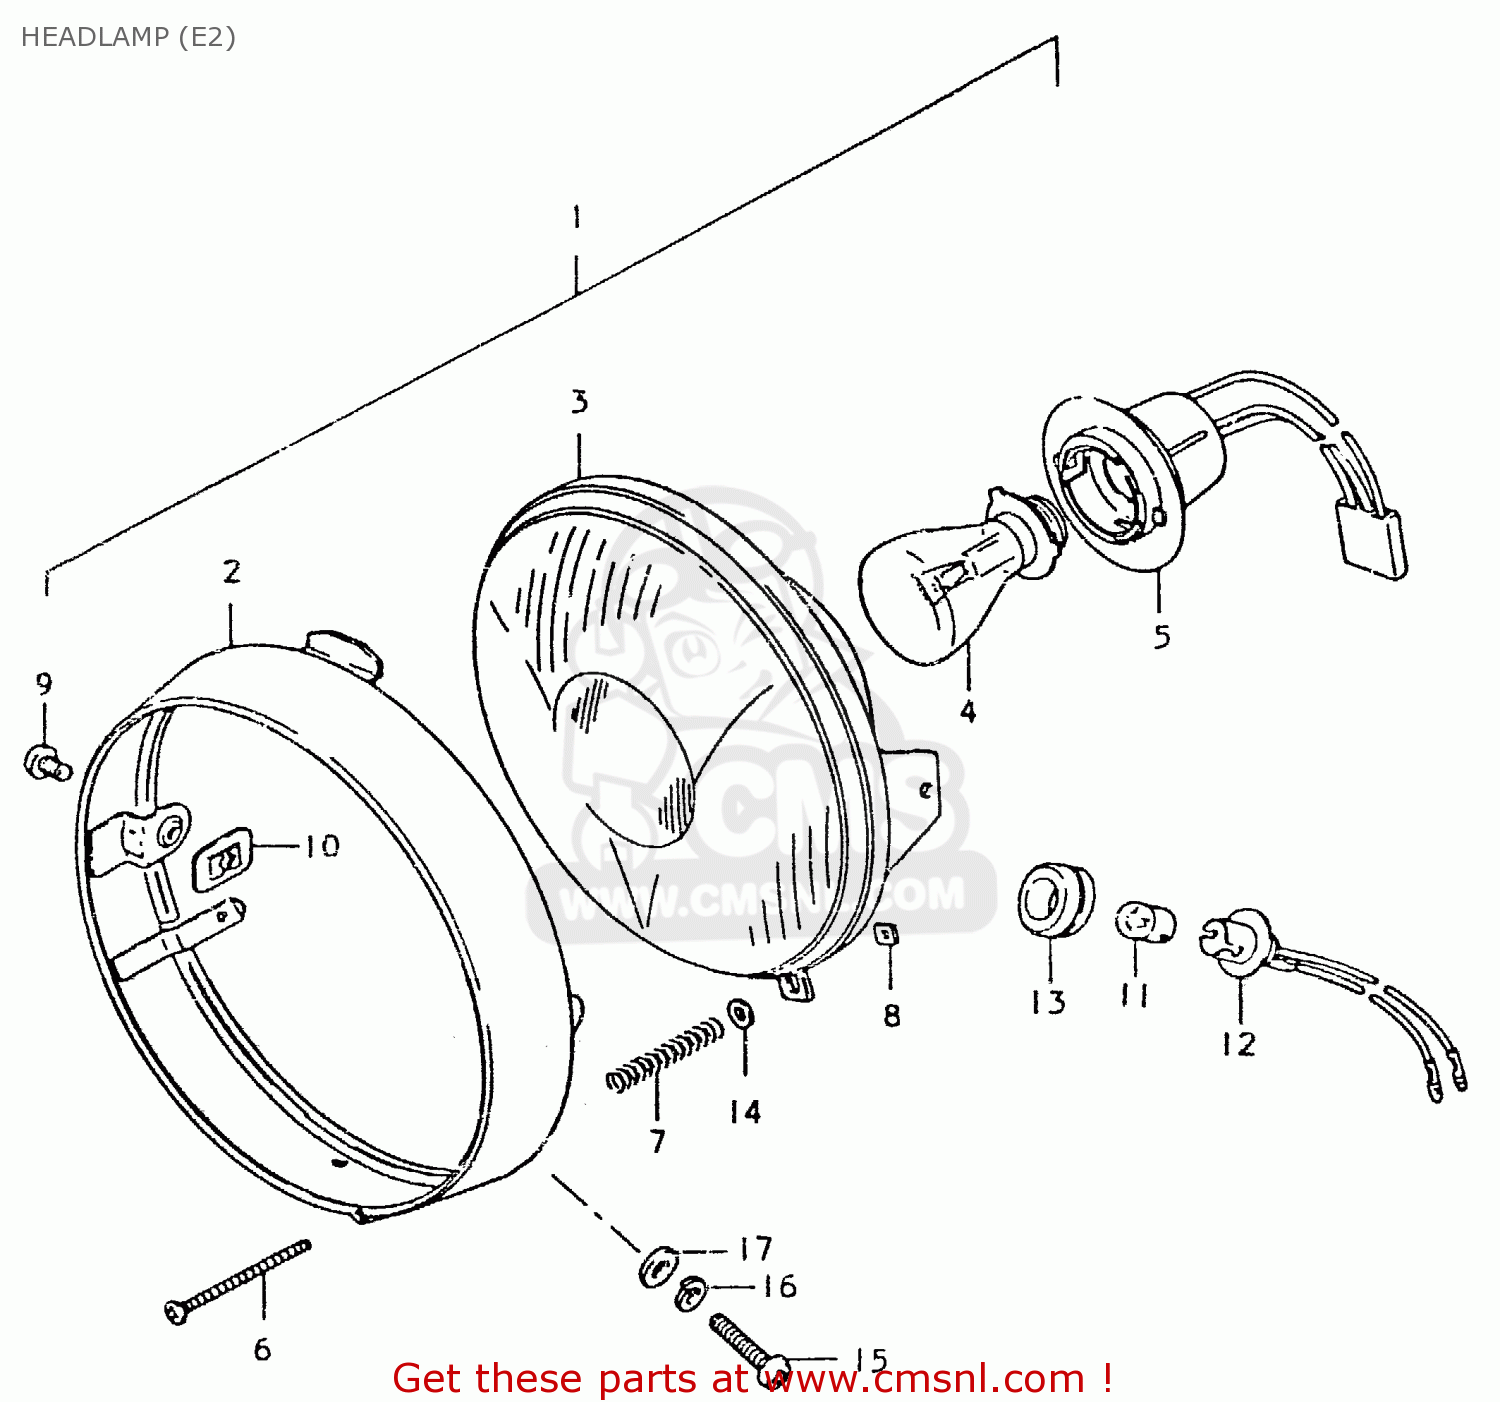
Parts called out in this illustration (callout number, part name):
1	HEADLAMP ASSY
2	RIM
3	UNIT
4	BULB(6V25/25W,STANLEY,A7007)
5	SOCKET
6	SCREW,HEADLAMP ADJUST
7	SPRING
8	NUT,HEADLAMP ADJUSTER
9	SCREW
10	NUT
11	BULB(6V/3W)
12	SOCKET
13	SEAL,PARKING BULB
14	WASHER
15	SCREW
16	LOCK WASHER
17	WASHER
